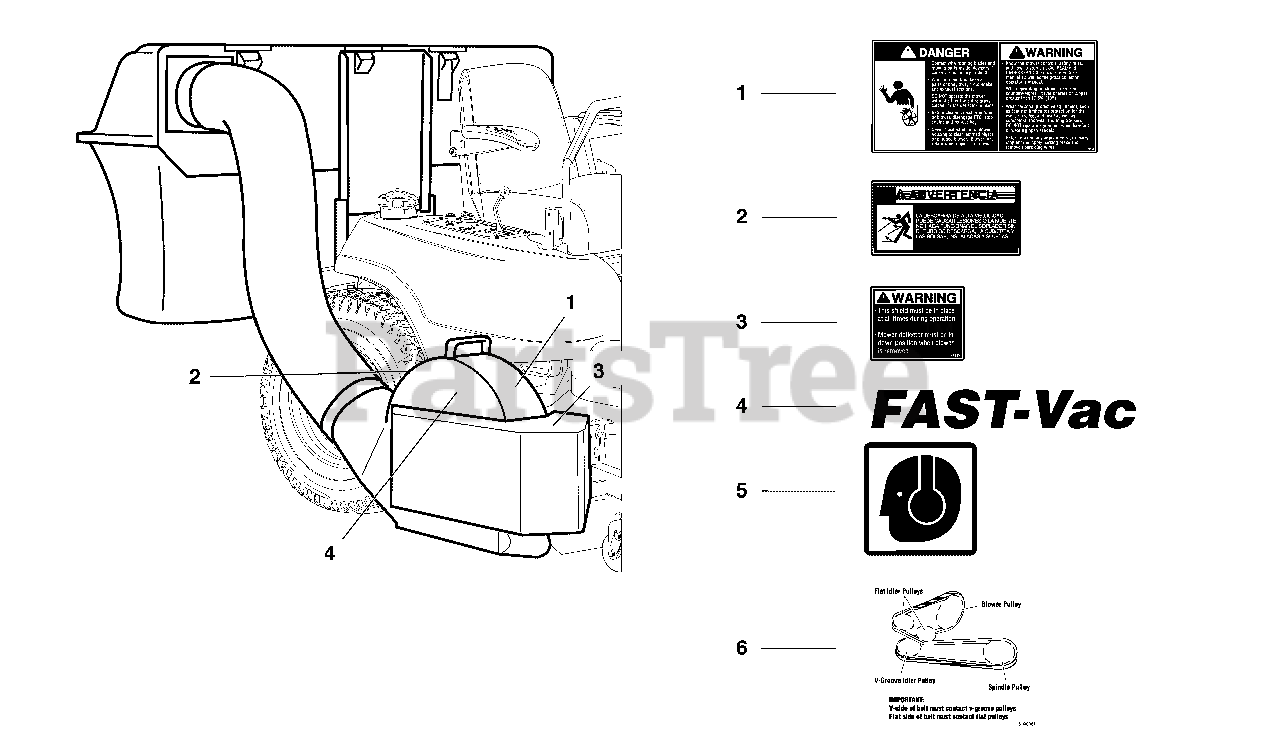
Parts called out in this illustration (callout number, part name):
1	DECAL, Danger/Warning
2	DECAL, Warning-Blower
3	DECAL, Warning-Shield
4	DECAL, Fast-Vac
5	DECAL, Ear Protection
6	DECAL, Belt Routing
